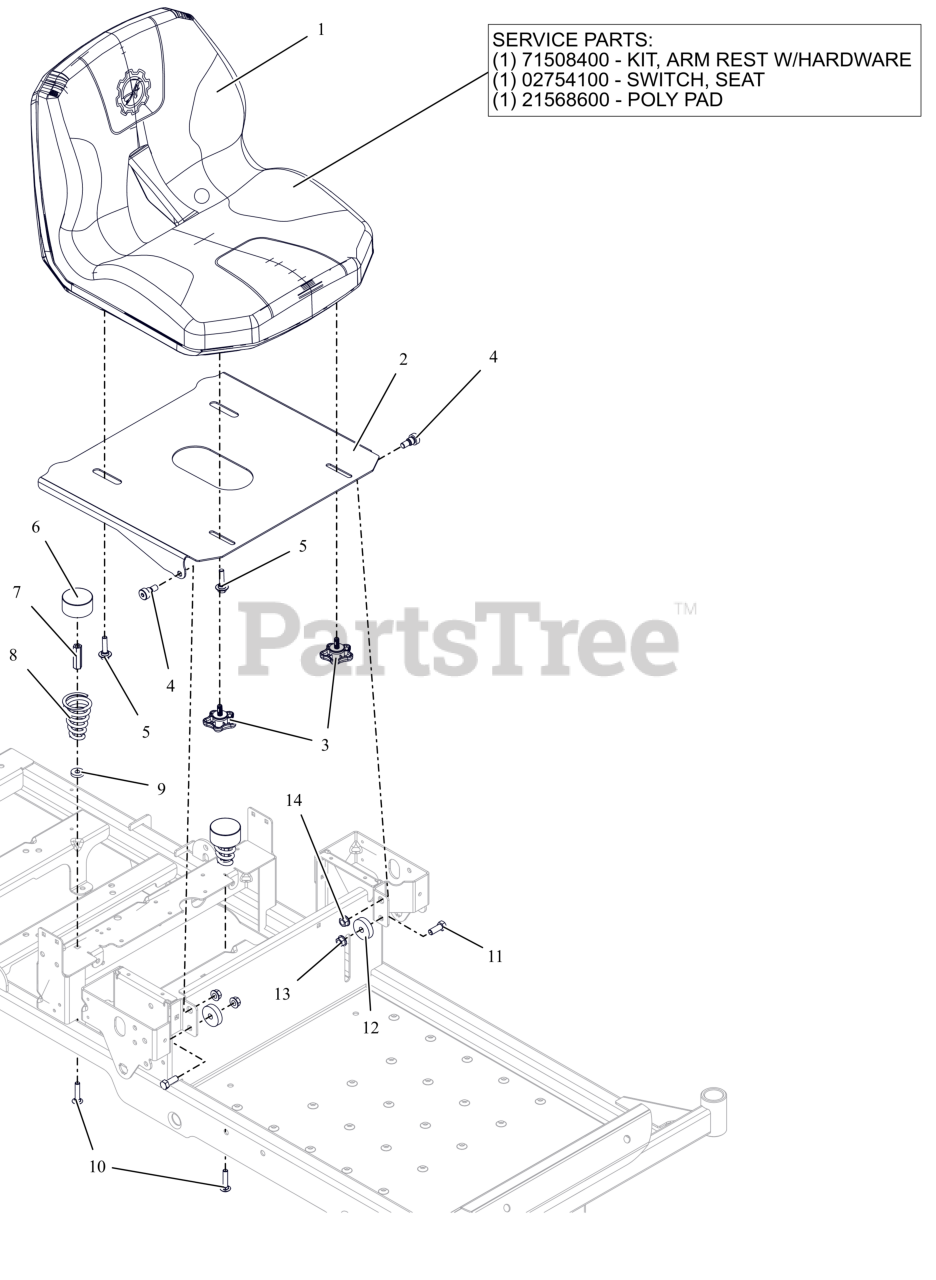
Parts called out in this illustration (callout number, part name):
1	SEAT- EDGE
1	KIT, ARMREST - EDGE
1	SWITCH- SNAP MTG N.O.
1	POLY PAD
2	PLATE, SEAT (ORANGE)
3	KNOB, WING STUDDED
4	BLT-SHLDR .38-16X.38 SKH
5	BOLT SHLDR .31-18 X .175
6	HUB CAP
7	NUT, COUPLING .31-18X1.75 ZCC
8	SPRING, SEAT
9	WSHR, FLT .328X.870X.179 ZCC
10	BLT,RHSN .31-18X1.50 G5 ZCC
11	BLT,HEX .38-16X1.00 G5 ZCC
12	SPACER, .39 X 1.50 X .380
13	NUT-LK-CTR-FLG .375-16 GF ZCC
14	NUT-LK-TOP-FLG .38-16 ZC120
